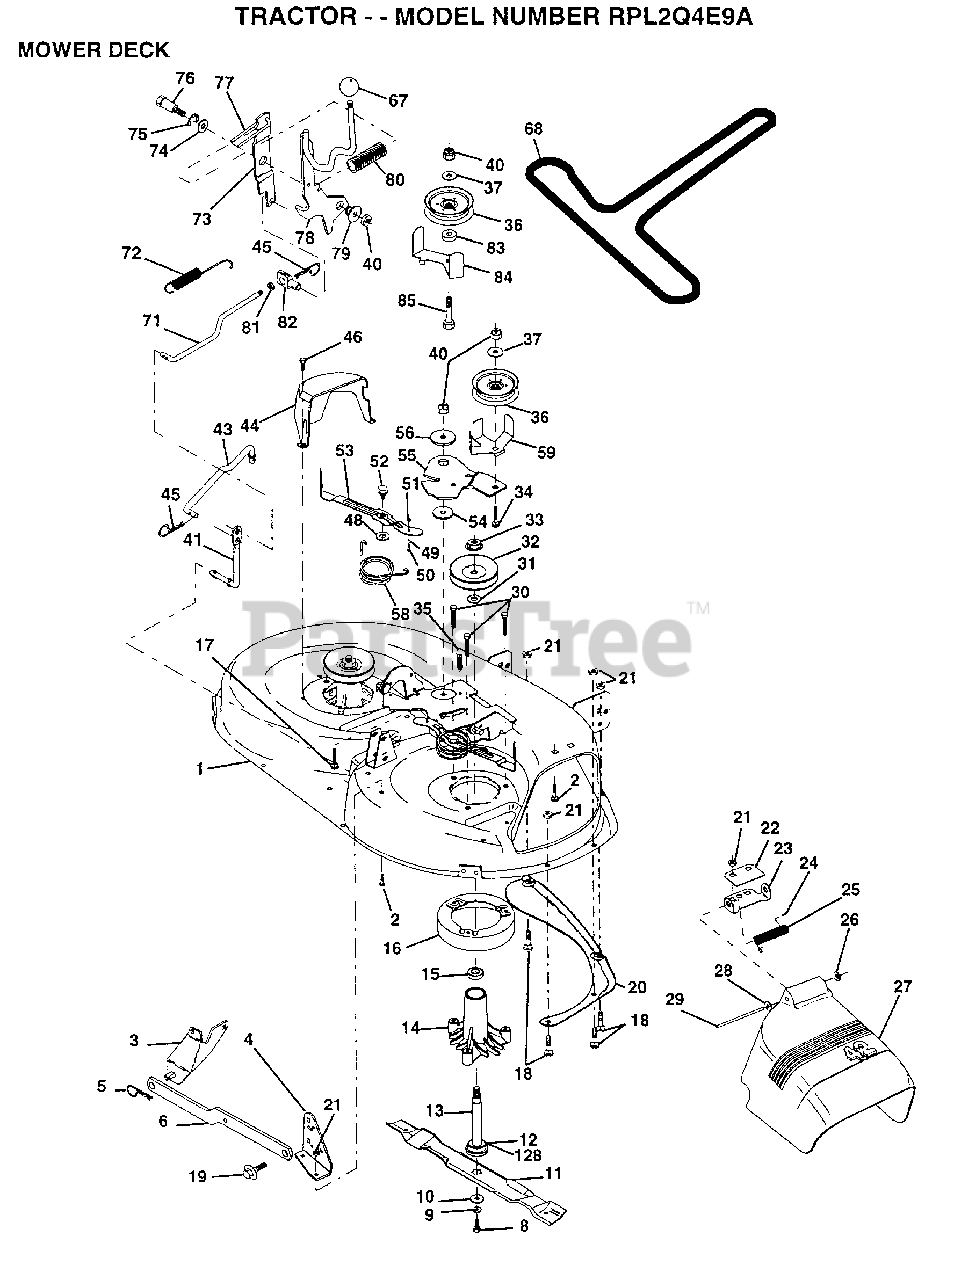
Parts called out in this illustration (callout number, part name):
1	DECK.WELD.42.
2	BOLT
3	BRKT ASM SWAY BAR
4	BRKT DECK SW BAR
8	BLADE BOLT
10	WASHER.HARD.BLADE
11	"BLADE.42"" HIPERF"
12	BEARING.BALL
14	HSG ASM MANDREL
15	BEARING
16	STRIPPER RND MWR
17	BOLT RDHD 3/8-16
18	BOLT
19	BOLT SHD 5/16-18
22	STIFFENER BRKT
23	DEFLECTOR BRKT
24	CAP-SLEEVE LT
25	SPRING TORSION
26	NUT PUSH M
27	DEFLECTOR.SHIELD
28	WASHER
29	HINGE ROD
31	WASHER
32	PULLEY.MANDREL.42
34	BOLT
35	XMAS TREE FASTNER
36	FLAT IDLER PULLEY
37	WASHER
41	PIVOT ROD
43	ROD CLUTCH W/NIBS
44	GUARD MAND LH BLK
45	RETAINER M
46	SCREW.1/4-20X5/8
48	HARD SMALL WASHER
50	SHOULDER BOLT
51	LOCKNUT
52	BOLT.SHLD.5/16-18
53	BRAKE PAD ARM ASM
54	HARDENED WASHER
56	SPACER RETAINER
58	SPRING TORSN BRAK
59	GUARD IDLER TUV
67	KNOB T (1/2-HOLE)
68	BELT.V.T-PATH
71	ROD CLUTCH 38/42
72	RETURN SPRING
73	CLUTCH ARM SECOND
74	WASHER
75	RING
76	SHOULDER BOLT
77	SPRING KEEPER
78	LEVER ASM CLT PRM
79	BUSHING
80	SPRING.CLUTCH.MWR
81	NUT
82	TRUNION ADJ
83	WASHER
85	BOLT RDHD 3/8-16
128	WASHER.FELT.
